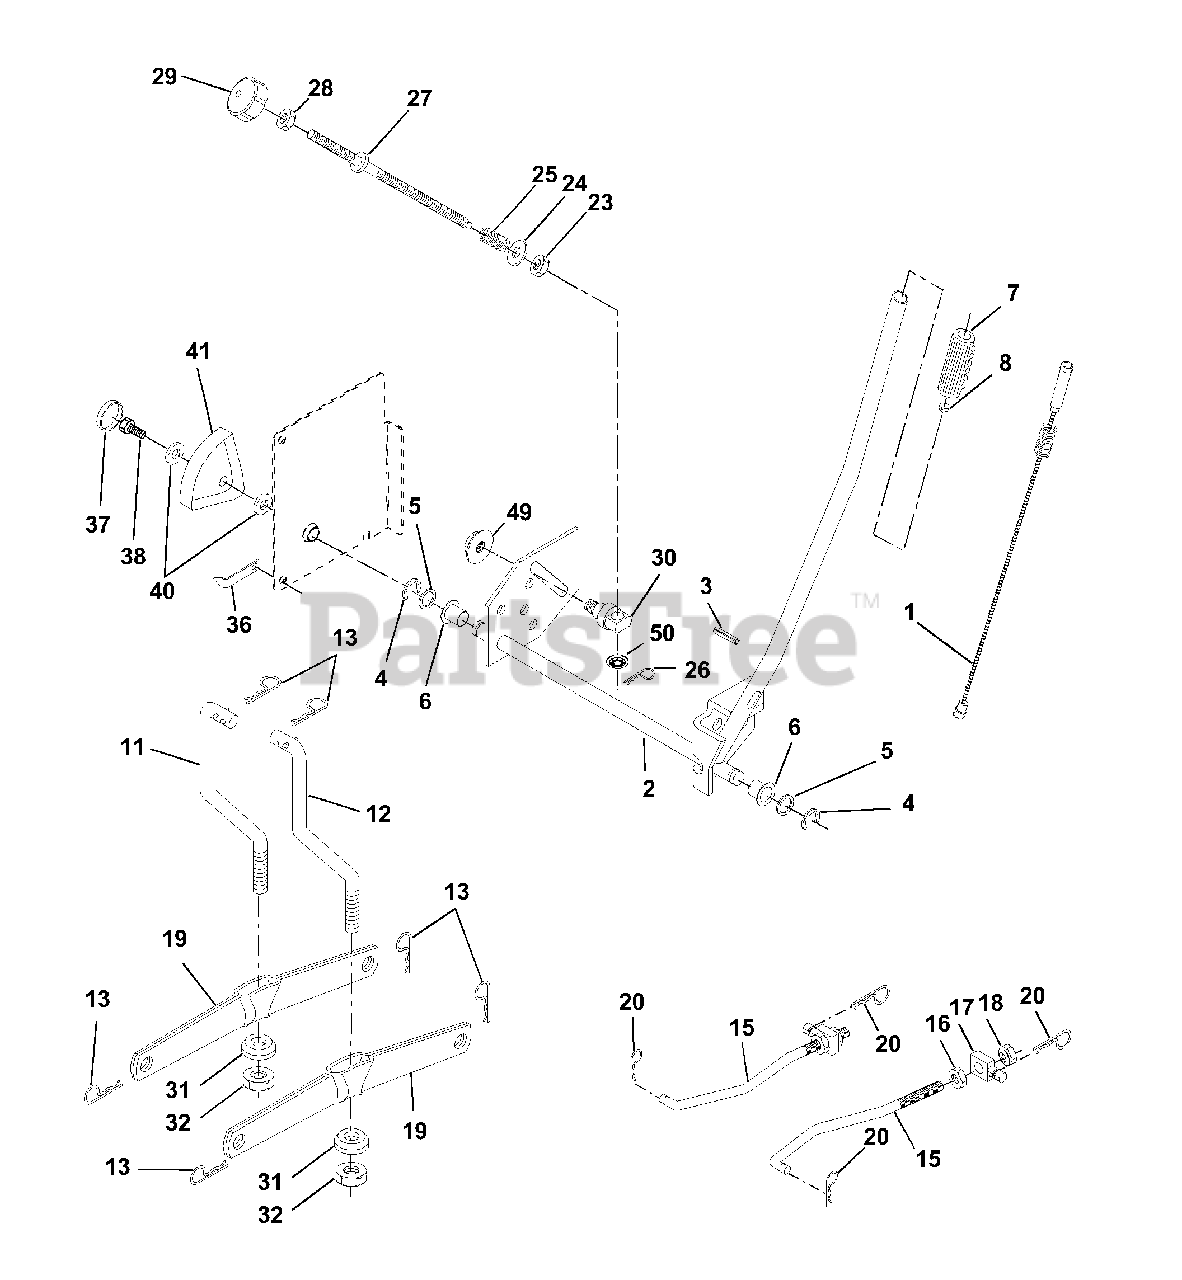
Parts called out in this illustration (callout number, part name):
1	Wire Asm Inner W/Plunger
2	Shaft Asm Lift
3	Pin Groove
4	E Ring #5133-62
5	Washer 29/32 x 1-1/4 x 21 Ga.
6	Bearing Nylon Blk .629 ID
7	Grip Handle Fluted
8	Button, Plunger
11	Link Lift Lh CRD
12	Link Lift Rh CRD
13	Retainer Spring
15	Link Front
16	Nut Jam Hex 1/2-13 Unc
17	Trunnion Blk Zinc
18	Nut Crownlock 1/2-13 Unc
19	Arm Suspension Rear
20	Spring Retainer
23	Nut Special
24	Washer 13/32 X 5/8 X 16 Ga
25	Spring
26	Retainer Clip
27	Rod Adjust Lift
28	Nut Hex Jam 3/8-16 Unc
29	Knob Infinite 3/8-16 Unc Black
30	Trunnion Infinite Height
31	Bearing Pvt. Lift Spherical
32	Nut Lock 3/8-24
36	Pointer Height Indicator
38	Screw Thdrol 5/16-18 x 3/4
40	Washer 11/32 x 1-1/2
41	Scale Ind Height Blk
49	Nut Hex Flange Lock
50	Nut Push Phos & Oil
52	Retainer Spring
